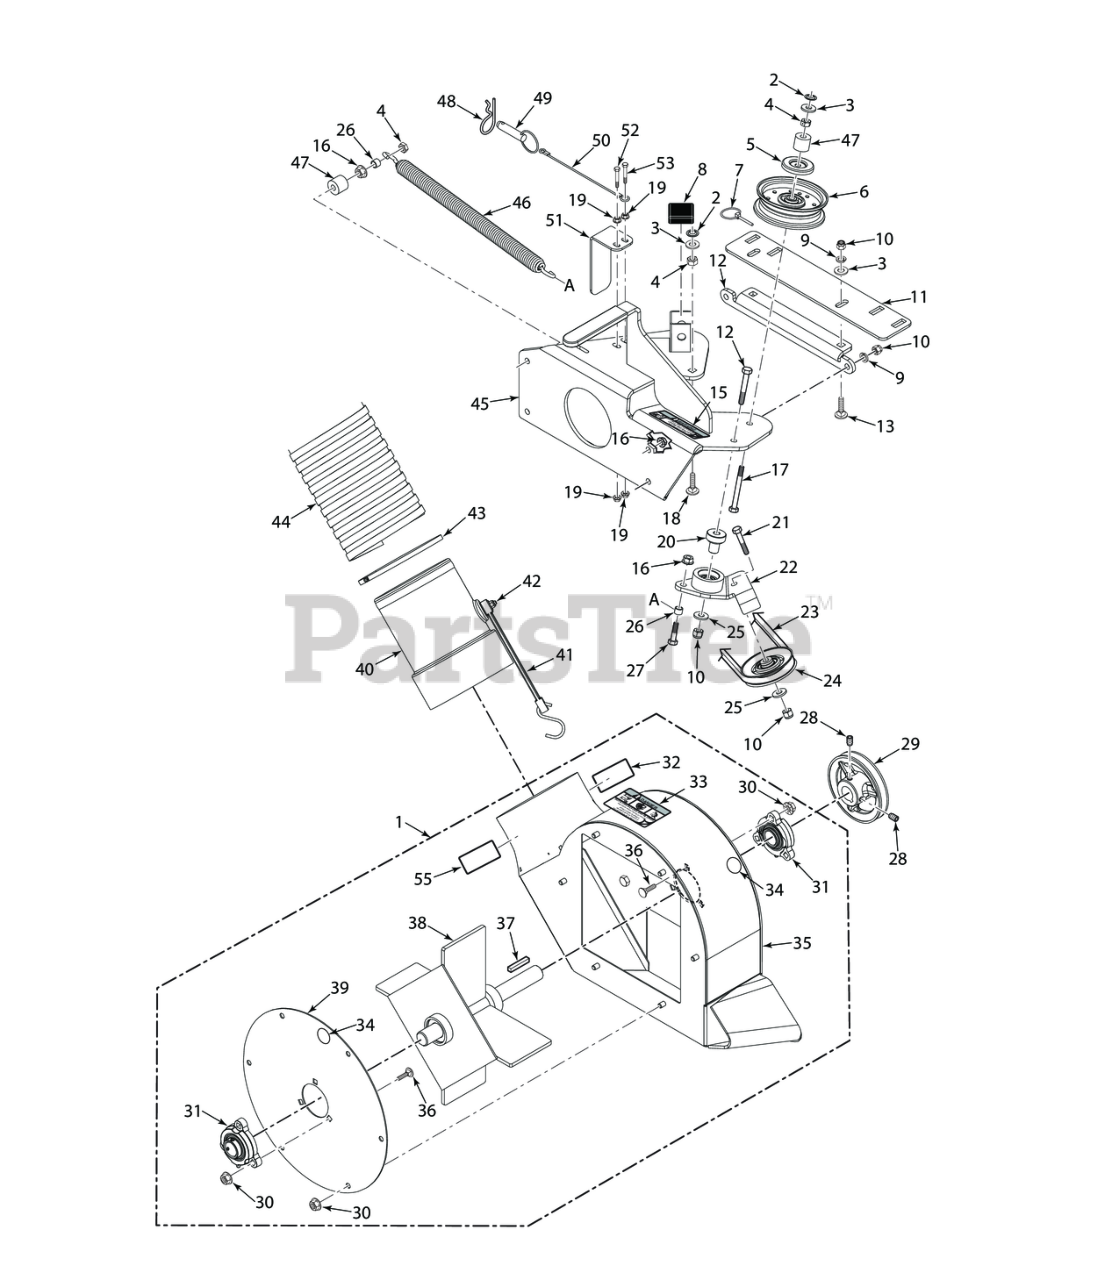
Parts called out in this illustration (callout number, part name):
1	Blowing Housing Assembly w/Fan
2	Nut, Push-On - 3/8" Dia.
3	Flatwasher, 3/8" Special (.391 x .938 x .105)
4	Bolt, Hex Head 3/8-16 x 1" Ser. Flg.
5	Quick Pin, 5/16" Dia.
6	Pulley, Idler 4" Dia. - 61" & 72"
7	Quick Pin, 5/16" Dia.
8	Cap, Square Vinyl
9	Lockwasher, 3/8" Spring, Kawasaki FX / FS
10	HEX NUT, ELASTIC STOP LOCK, 3/8-16
11	Plate, Blower Catch
12	Plate, Catch Mounting
13	SHORT SQ. NECK CARRIAGE BOLT, 3/8-16 X 1-1/4"
14	Bolt, Hex Head 3/8-16 x 2-1/4" - 61"
15	Decal, Warning - Belt Cover
16	NUT, 3/8-16 SERRATED FLANGE HEX HEAD
17	Bolt, Hex Head 3/8-16 x 3-1/2" Full Thread
18	Bolt, RDHD Carr. 3/8-16 x 1-1/2 (52" & 61")
19	NUT, 1/4-20 SERRATED FLANGE HEX HEAD
20	Pivot, Idler - 61" & 72"
21	Capscrew, Hex Head 3/8-16 x 2.0"
22	Idler Arm Assembly
23	Belt (52)
24	Pulley, 3-1/2" O.D., GC-STT 52"
25	Flatwasher, 3/8 (.391 x .938 x .105 HD) Grade 8
26	Spacer, Deck Assist
27	Bolt, Hex Head 3/8-16 x 1-1/4" Grade 8
28	Setscrew, Hex Socket Knurl Cup Pt. 5/16 - 18 (nylock)
29	Pulley, 4-3/4" O.D. - 1" Bore
30	Nut, Serrated Flange 5/16-18 (Right Front Engine Mounting, Briggs and Kohler Only)
31	Bearing Assembly
32	Decal, Blower
33	Decal, Danger
34	Decal, Grease Point
35	Blower Housing Weldment w/Decals
36	Bolt, Carriage 5/16-18x1" (large frame units only)
37	KEY 1/4 X 1/4 X 1 1/2"(FOR 1" CRANKSHAFT
38	Fan Weldment, Narrow
39	COVER, BLOWER HOUSING
40	Adapter, Blower GC-STC,
41	Rubber Strap 7-3/4"
42	SERR. FLG. HEX HEAD CAPSCREW, 5/16-18 X 3/4
43	Clamp, 6-1/2"
44	Hose, 6" x 56"
45	Blower Mounting Frame w/ Decal
46	Spring, Helper (61" Cutter Deck Only)
47	SPACER, J-PULL ROD
48	Hair Pin Cotter, .243 x 4"
49	Pin, Ring 1/2" x 2-1/4"
50	Lanyard, Deck Height Pin
51	Belt Cover
52	Bolt, Hex Head, 1/4-20 x 1-1/2"
53	SERR. FLG. HEX HEAD CAPSCREW, 5/16-18 X 3/4
54	Grip, Deck Latch Lever
55	Decal, Rotating Blower
